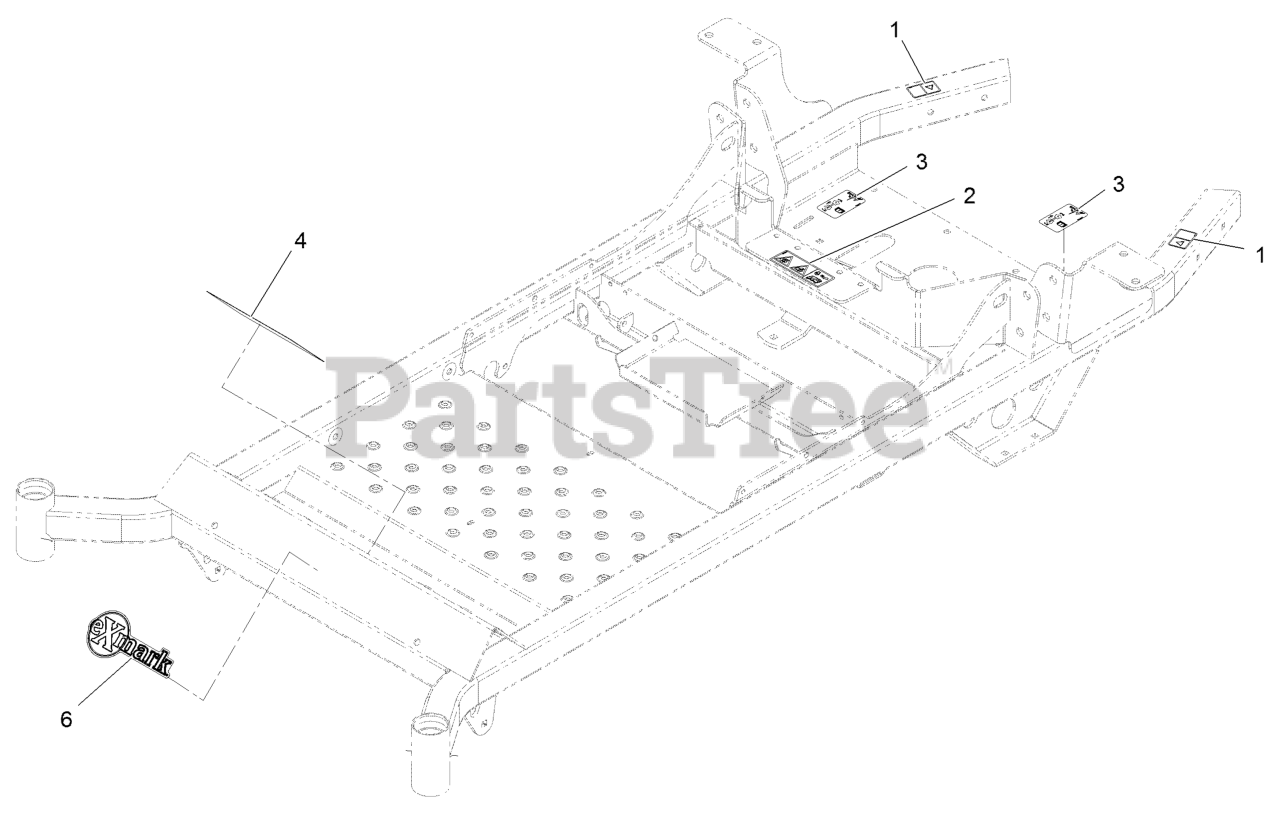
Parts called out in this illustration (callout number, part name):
1	DECAL-WARNING
2	DECAL-WARNING
3	DECAL-RELEASE, DRIVE
4	DECAL-DANGER
6	DECAL, EXMARK LOGO
